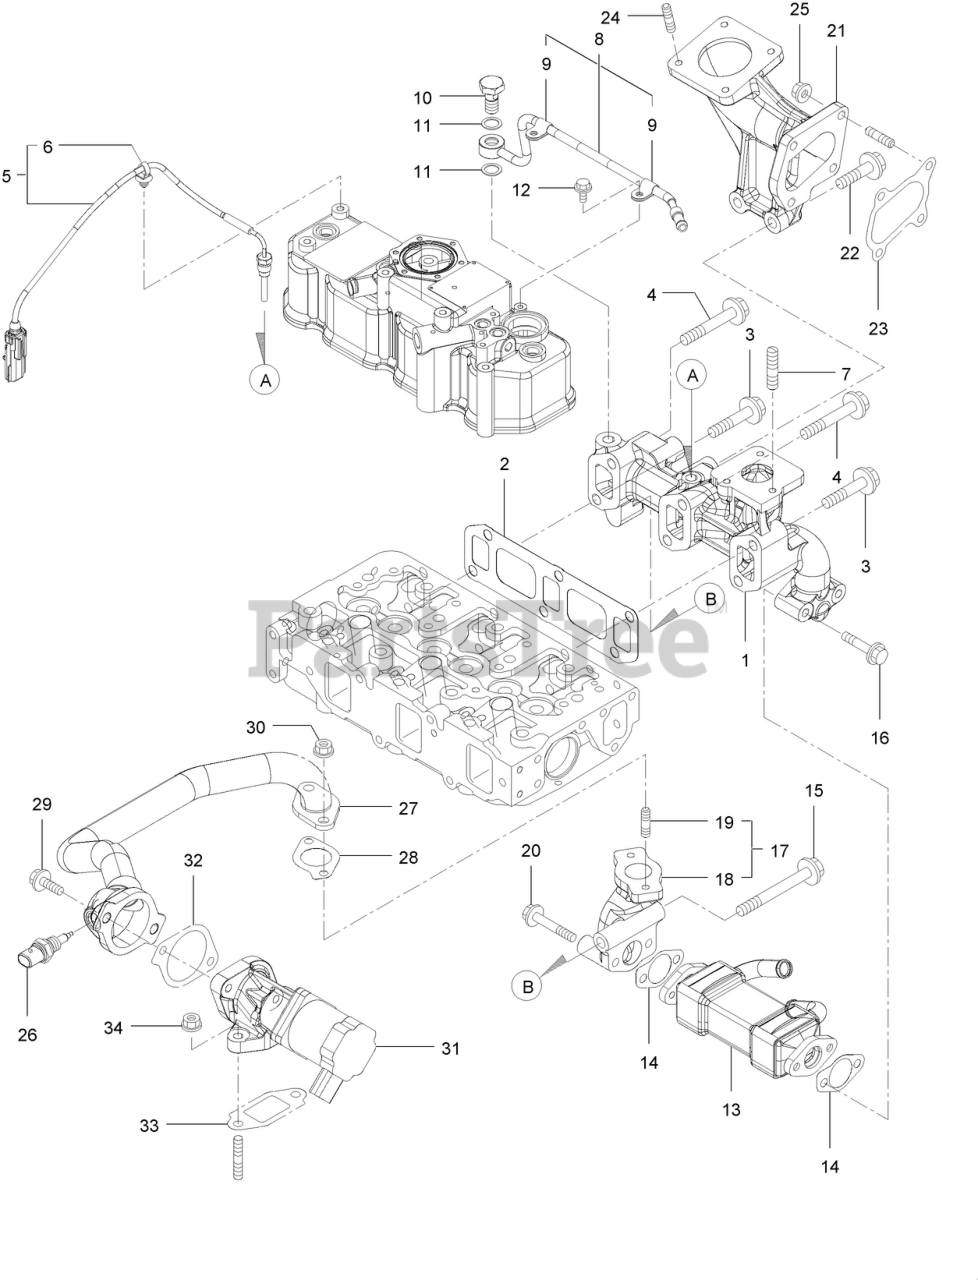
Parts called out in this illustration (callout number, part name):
1	MANIFOLD-EXHAUST
2	GASKET-MANIFOLD, EXHAUST
4	BOLT, M10X65 10.9T
5	SENSOR-TEMP, EXHAUST
6	BAND-CLIP
8	EXHAUST PIPE ASM
10	BOLT-JOINT, PIPE
11	GASKET
13	COOLER-E G R
14	GASKET-COOLER, E G R
17	E G R PIPE ASM
18	PIPE-OUT, E G R
21	PIPE, EXHAUST
23	GASKET-OUT, T C
26	SENSOR-GAS TEMP, E G R
27	E G R PIPE ASM
28	GASKET
31	VALVE-E G R
32	GASKET-INTAKE VALVE, E G R
33	GASKET-OUT VALVE, E G R
